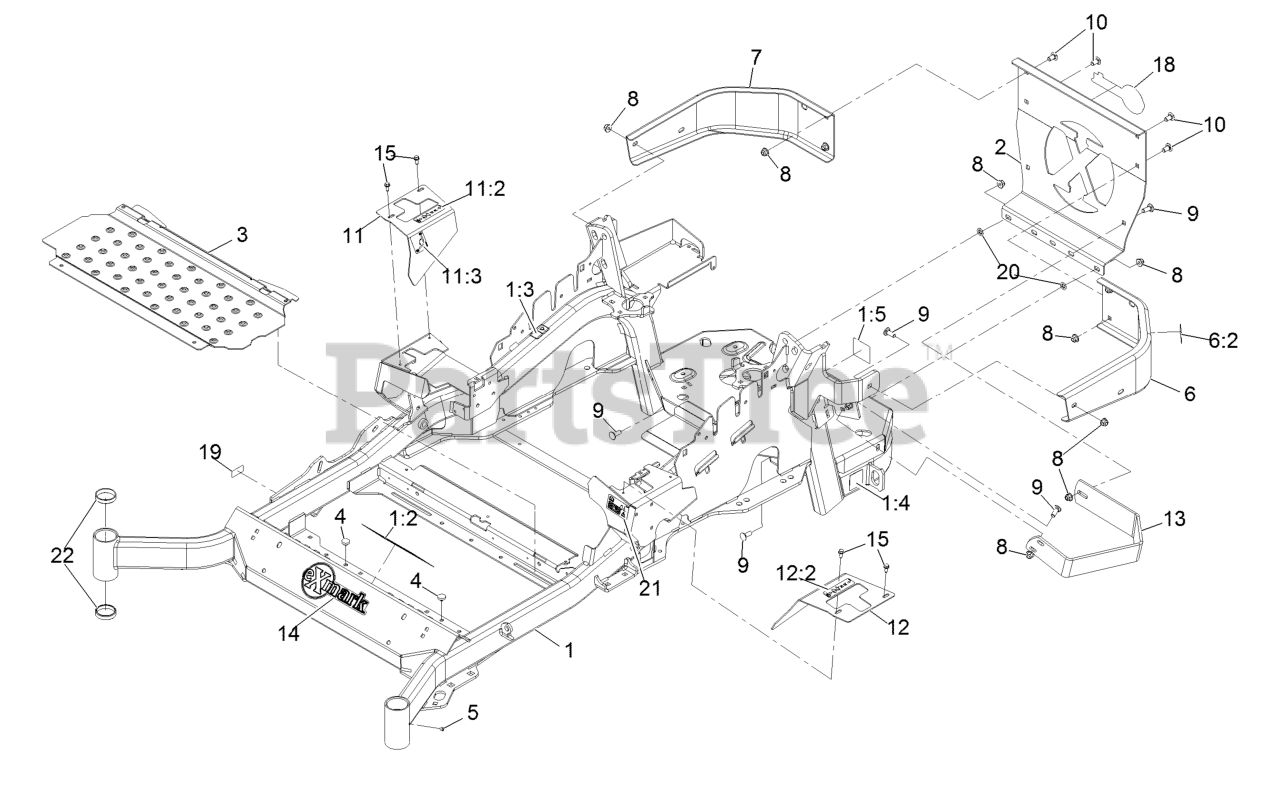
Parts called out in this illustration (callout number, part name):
1	MAINFRAME ASM
1:2	DECAL-DANGER
1:3	DECAL-WARNING
1:4	DECAL-HAZARD, PINCHED FINGER
1:5	DECAL-SPARK ARRESTER
2	PLATE,REAR GUARD
6	LH BUMPER ASM
6:2	DECAL-WARNING
7	BUMPER-RH
8	NUT-HF, NI
9	SCREW-CARR
10	SCREW-CARR
11	RH MOTION CONTROL COVER ASM
11:2	DECAL-CONTROL, MOTION
11:3	DECAL-PARK BRAKE, CE
12	LH MOTION CONTROL COVER ASM
12:2	DECAL-CONTROL, MOTION
13	GUARD-MUFFLER
14	DECAL-EXMARK LOGO
15	SCREW-HWH
18	DECAL-EXMARK LOGO
19	Decal-Patent
20	NUT-PUSH
21	DECAL-FUEL FILL, CE
22	CUP-BEARING
